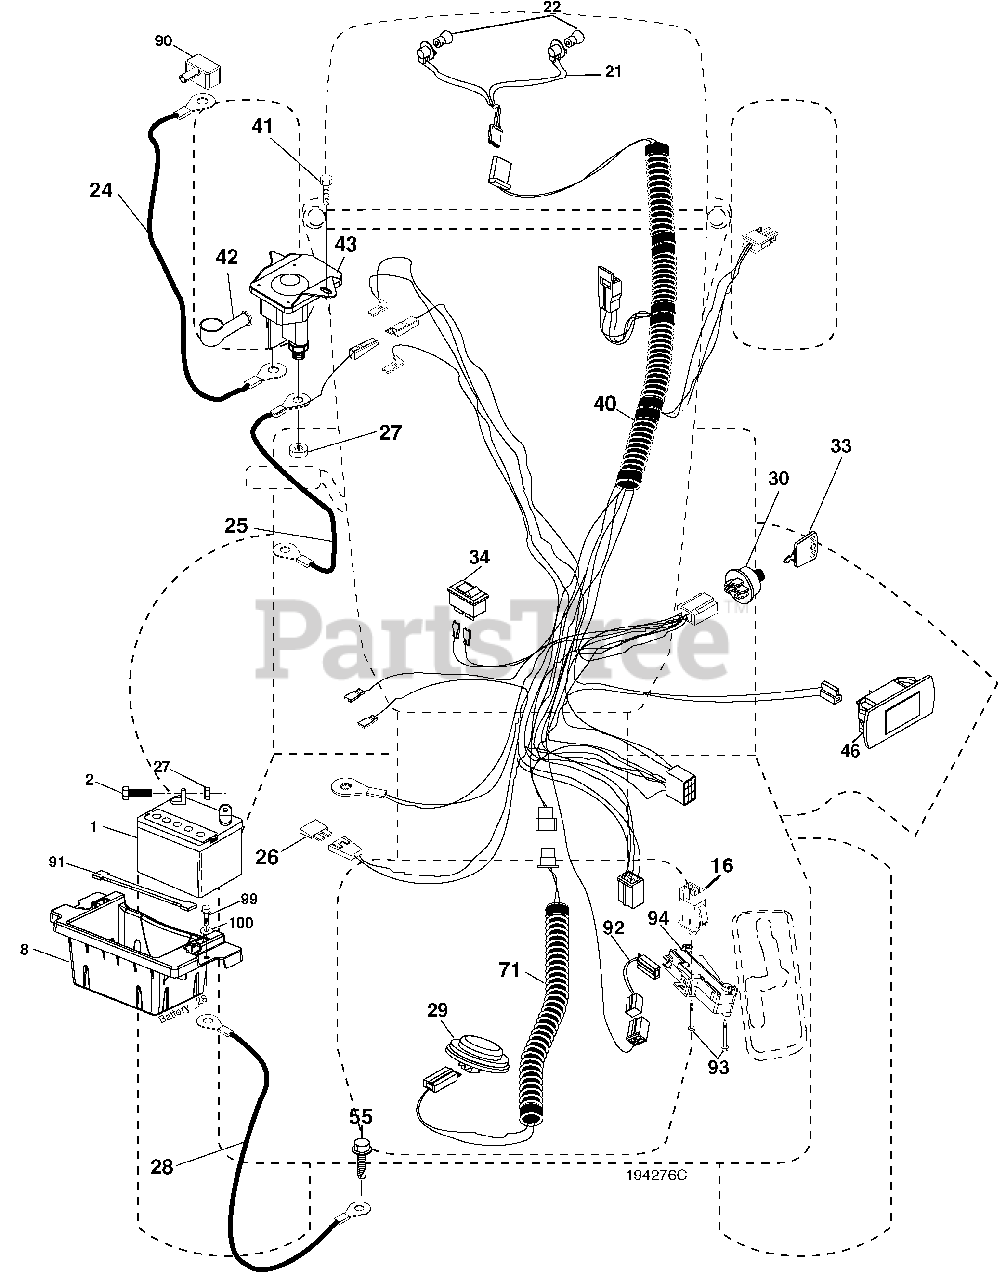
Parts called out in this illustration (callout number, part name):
1	Battery
2	Bolt Hex Head 1/4-20 x 3/4
8	Box Battery
16	Switch Interlock Push-In
21	Harness Socket Light W/4152J
22	Bulb Light
24	Cable Battery
25	Cable Starter
26	Fuse
27	Nut Keps Hex 1/4-20 unc
28	Cable, Ground
29	Switch, Seat
30	Switch, Ign
33	Key, Ignition
34	Switch Light / Reset
40	Harness Ign.
41	Screw Thd Cut 1/4-20 x 1/2
42	Cover, Terminal
43	Solenoid
46	Gauge Hourmeter
55	Screw Thdrol 5/16-18 x 3/4 TYTT
71	Harness Ign. Dash
90	Cover Terminal Battery
91	Strap Battery Mount Front
92	Harness Pigtail
93	Screw Plastite 10-14 x 2.0
94	Module Reverse ROS
99	Screw Hexwsh Thdrol 1/4-20 x 3/4
100	Washer 9/32 x 7/8 x 16 Ga.
